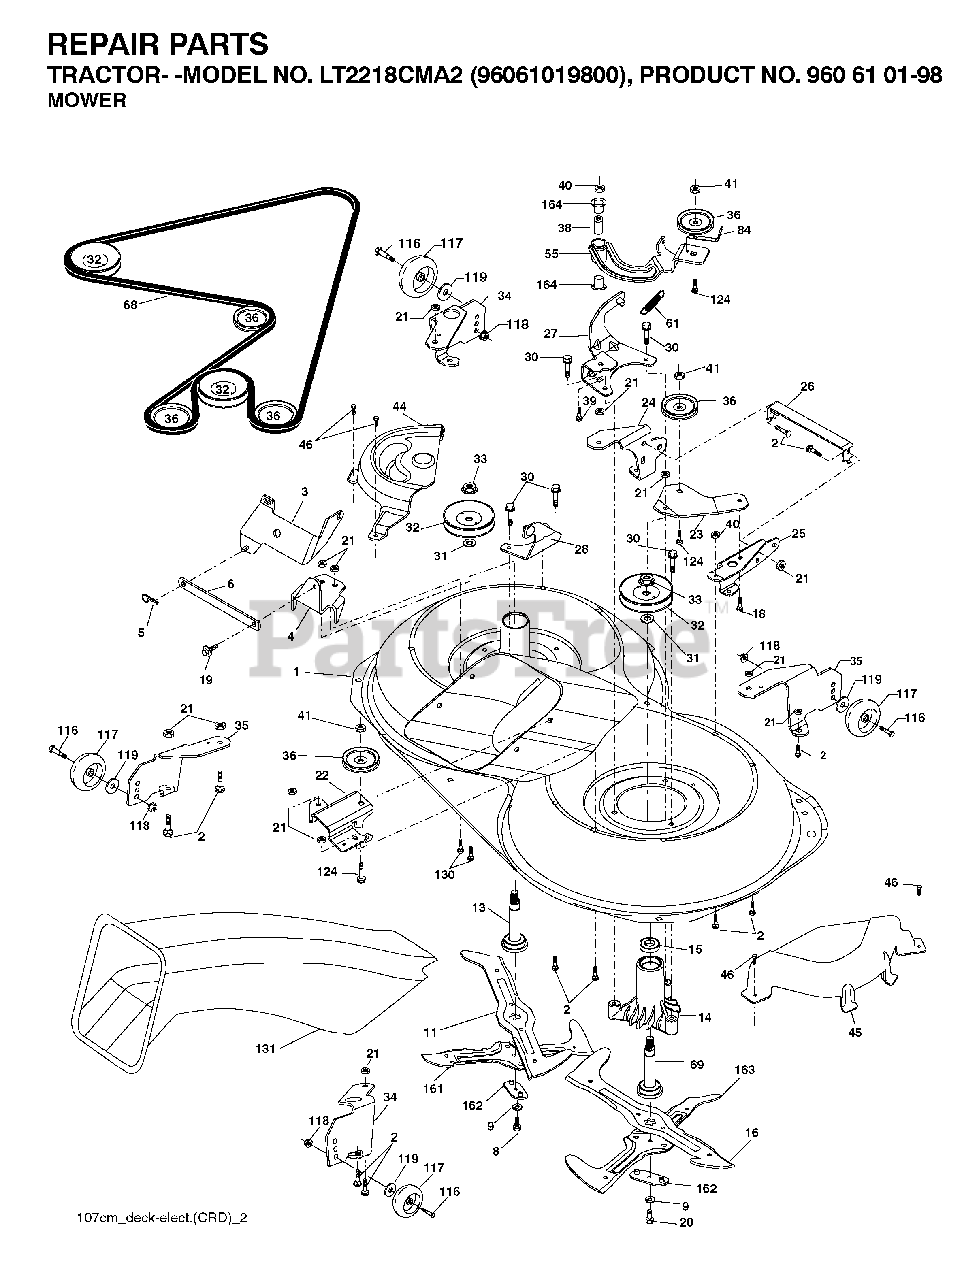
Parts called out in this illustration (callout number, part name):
2	BOLT
3	BRACKET
5	RETAINER-SPRNG RB
6	BAR SWAY
9	LOCKWASHER
11	BLADE.3N1.LH.CRD
13	SHAFT ASM VENT
14	HSG MANDREL
16	BLADE.3N1.RH.CRD
19	BOLT SHD 5/16-18
21	LOCKNUT
22	BRACKET
23	BRACKET
27	BRACKET
30	SCREW, WASHER HEAD
31	WASHER.SPACER.MANDREL
33	NUT.FLANGE.LOCK.TOP
36	PULLEY.IDLER.4.25
40	LOCKNUT
41	NUT LOCK FLG 3/8-16 UNC
45	MANDREL COVER
46	SCREW.1/4-20X5/8
55	ARM IDLER
68	HEX-BELT 107 MOWER
69	SHAFT.ASM.W/LWR.BRG.RH.THREAD
84	KEEPER, BELT IDLER
116	BOLT.SHOULDER.3/8-16X3-5/8
117	WHEEL. GUAGE RALLY
118	NUT LOCK FLG 3/8-16 UNC
124	BOLT.3/8-16X1.50
131	CHUTE BAGGER
164	BRNG T
